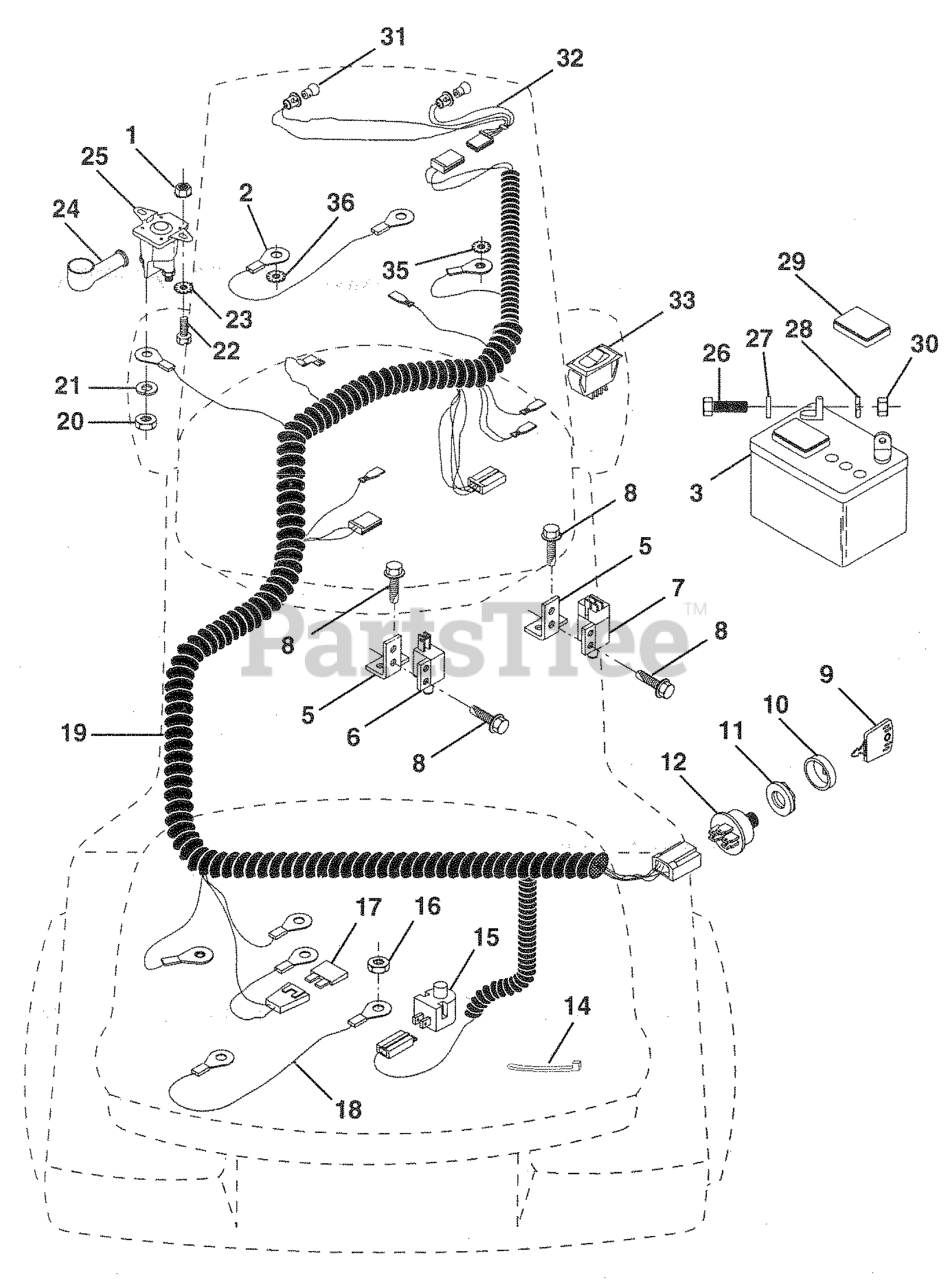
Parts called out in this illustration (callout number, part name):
1	NUT
2	CABLE ASSY
3	BATTERY
5	BRACKET LT
6	SWITCH-INTER. GT
7	SWITCH INTERLOCKT
9	KEY.MOLDED.GENERIC
10	COVER KEY IGNITIO
11	NUT IGNITION
12	SWITCH
14	TIE GUIDE
15	RP.SWITCH.PLUNGER.NC.GRAY
16	NUT
18	CABLE.BATTERY.6GA.16"RED
19	IGNITION HARNESS
20	NUT
21	LOCKWASHER
22	BOLT
23	Washer, Lock Ext. Tooth 1/4
24	TERMINAL COVER
25	SOLENOID
26	BOLT.HEX.1/4.X.3/4.DICHROMATE
27	WASHER
28	LOCKWASHER
29	CAP BATTERY NLA
30	NUT
32	SOCKET LIGHT HARNESS
35	LOCKWASHER
